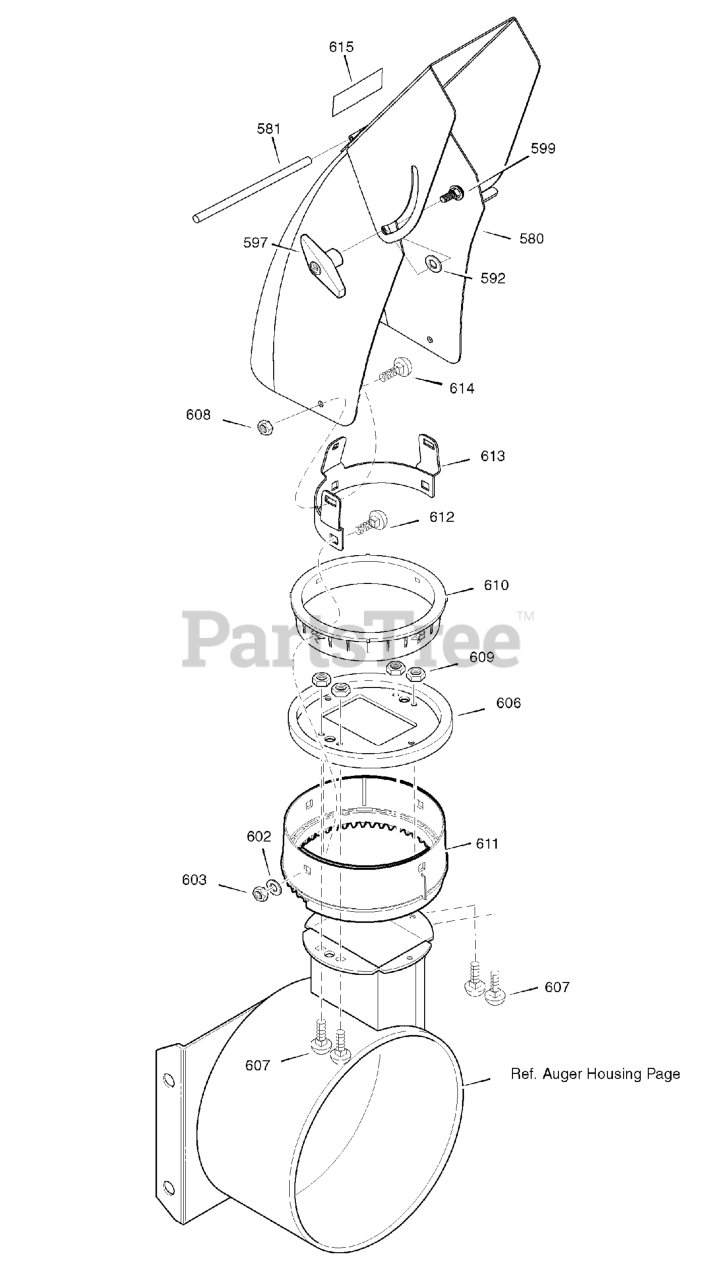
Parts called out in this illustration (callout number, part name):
580	DISCHARGE CHUTE
592	WASHER, PLASTIC
597	KNOB, T 3.00
599	BOLT, 5/16-18 X 1.50
602	WASHER, FLAT
603	NUT, 5/16-18 HEXNYL
606	CHUTE COLLAR
607	SCREW, 1/4-20 X 0.75
608	NUT, Hex Flange, 1/4-20
609	NUT, 1/4-20 HEX NYLOCK
610	RETAINER RING INNER
611	RETAINER RING OUTER
612	BOLT, 5/16-18 X 1.00
613	ADAPTER, Chute Ring
614	CARRIAGE BOLT, 1/4-20 x 3/4, G5
615	DECAL, Hinge
